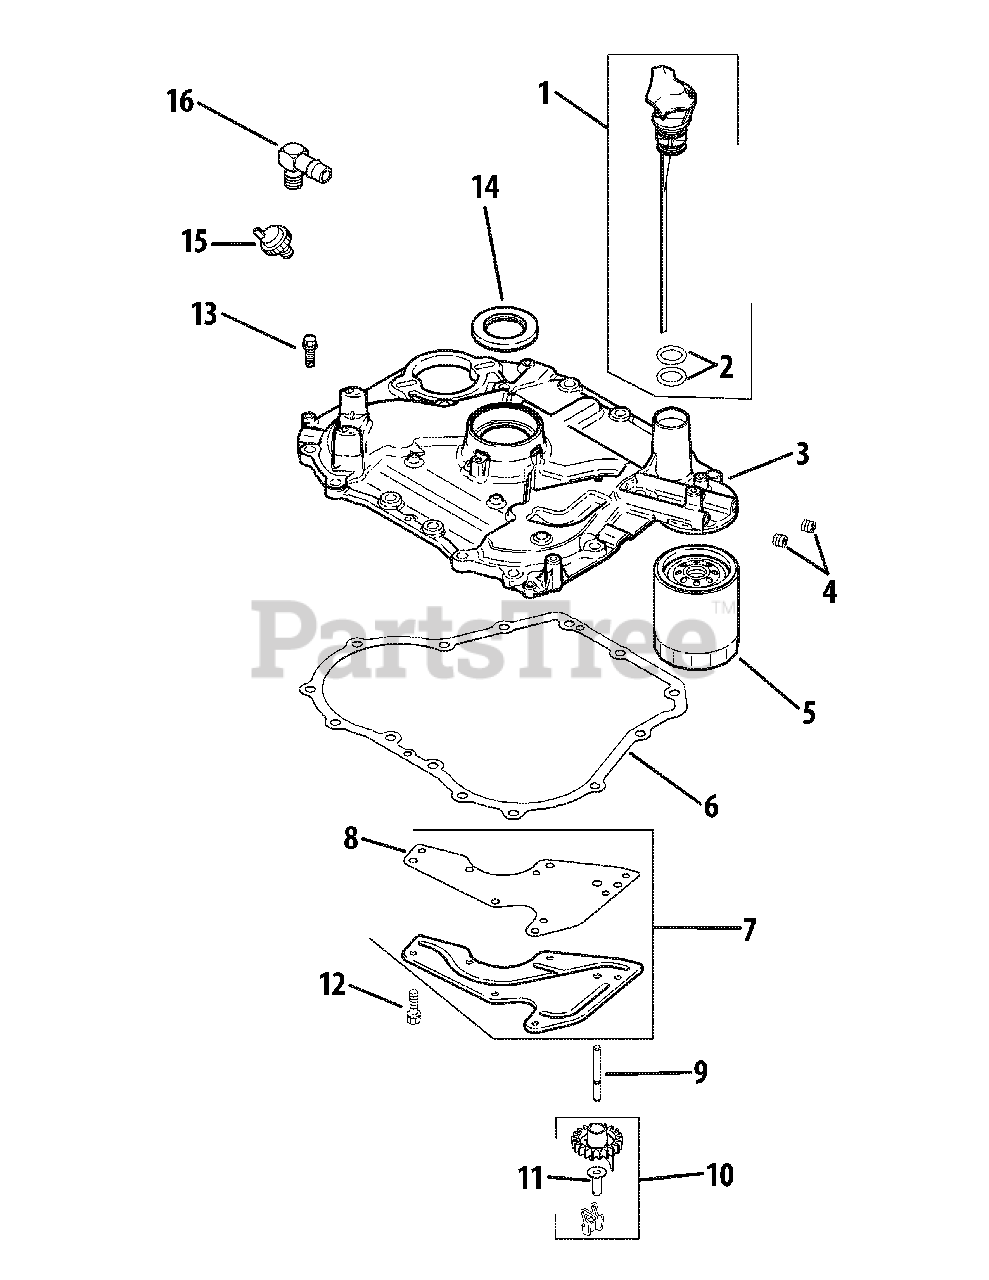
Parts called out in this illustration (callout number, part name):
1	Dipstick w/ 2 O-Rings
2	O-Ring
3	Closure Plate Assembly Kit
4	CTSK Pipe Plug, 1/8 "
6	Closure Plate Gasket
7	Oil Passage Cover Kit
8	Oil Passage Gasket
9	Governor Cross Shaft
10	Governor Gear Kit
11	Governor Regulating Pin
12	Flg Thd Frm Screw, M5 x 0.8 x 13
13	Hex Flange Screw, 1/2 Dog Point
14	Oil Seal
15	Oil Pressure Switch
16	90 Connector Hose
